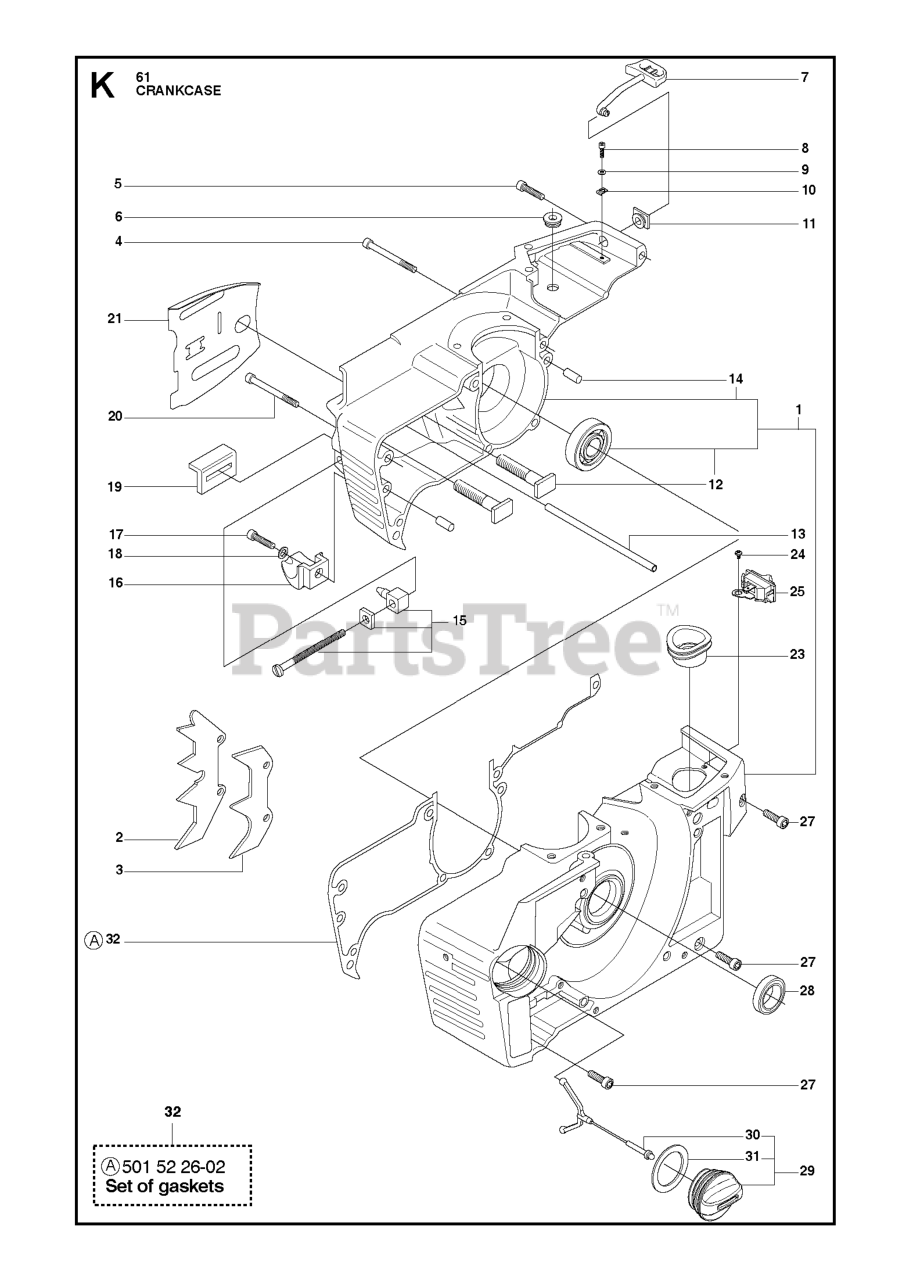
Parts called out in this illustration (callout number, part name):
1	CRANKCASE CPL
2	FELLING DOG
3	FELLING DOG
4	SCREW MC6S 5X35
5	SCREW ITXSCM
7	CHOKE CONTROL
8	SCREW MC6S 4X16
9	WASHER 4.2X9
13	HOSE
13	OIL TANK VENT
13	SPIRAL PIN 3.5X18
14	PIN 5X14
15	CHAIN TENSIONER
16	CHAIN CATCHER
17	SCREW MC6S 5X12
19	CHAIN GUIDE
20	SCREW MC6S 5X50
21	PROTECTION PLATE
25	SWITCH ON/OFF
27	SCREW MC6S 5X12
28	SEALING RING
31	OILCAP GASKET
32	GASKET SET NLA
